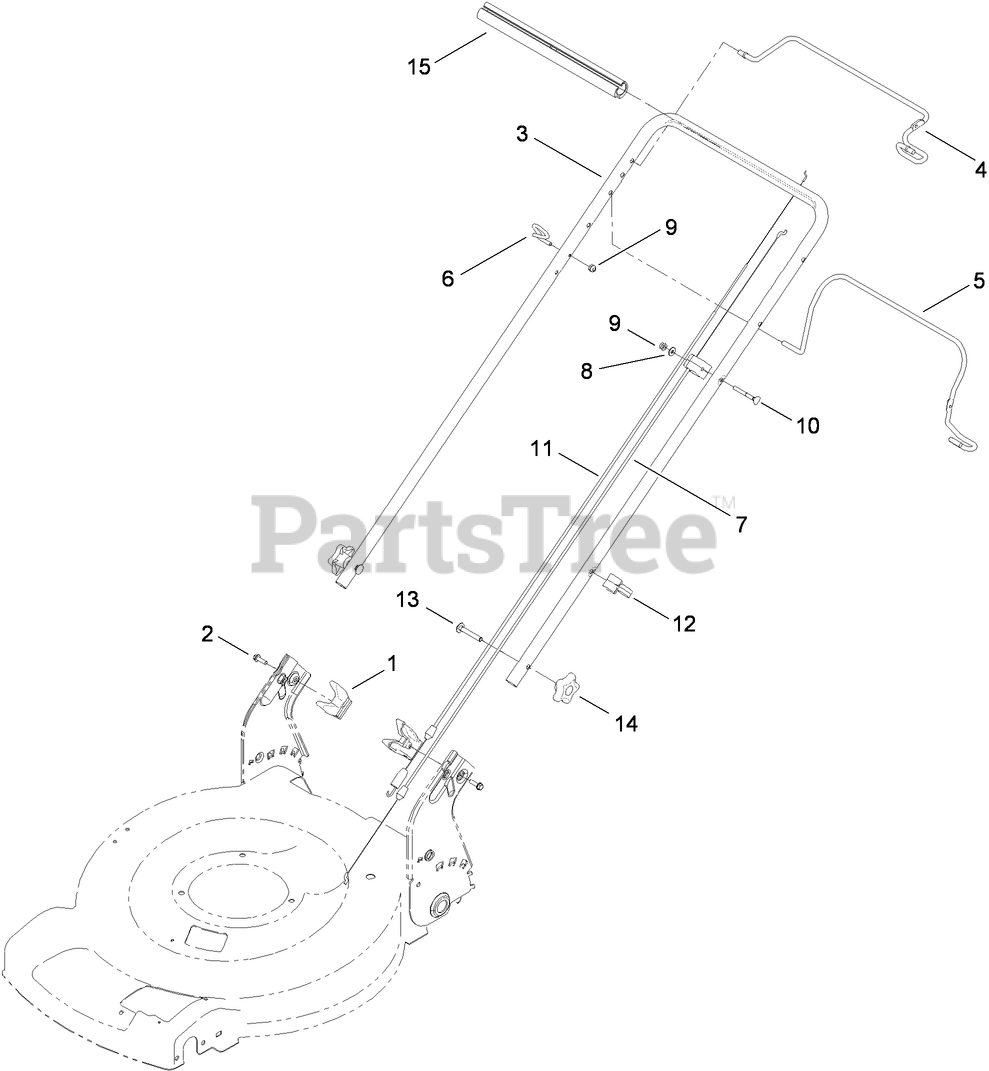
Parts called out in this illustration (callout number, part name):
1	ANCHOR-BAG
2	SCREW-HWH
4	BAIL-TRACTION
5	BAIL-BRAKE
6	GUIDE-ROPE
7	CABLE-BRAKE
8	WASHER-FLAT
9	NUT-LOCK, NI
10	SCREW-HANDLE
11	CABLE-TRACTION
12	GUIDE-CABLE
13	BOLT-CARR
14	KNOB-HANDLE
15	GRIP-HANDLE, COMFORT
